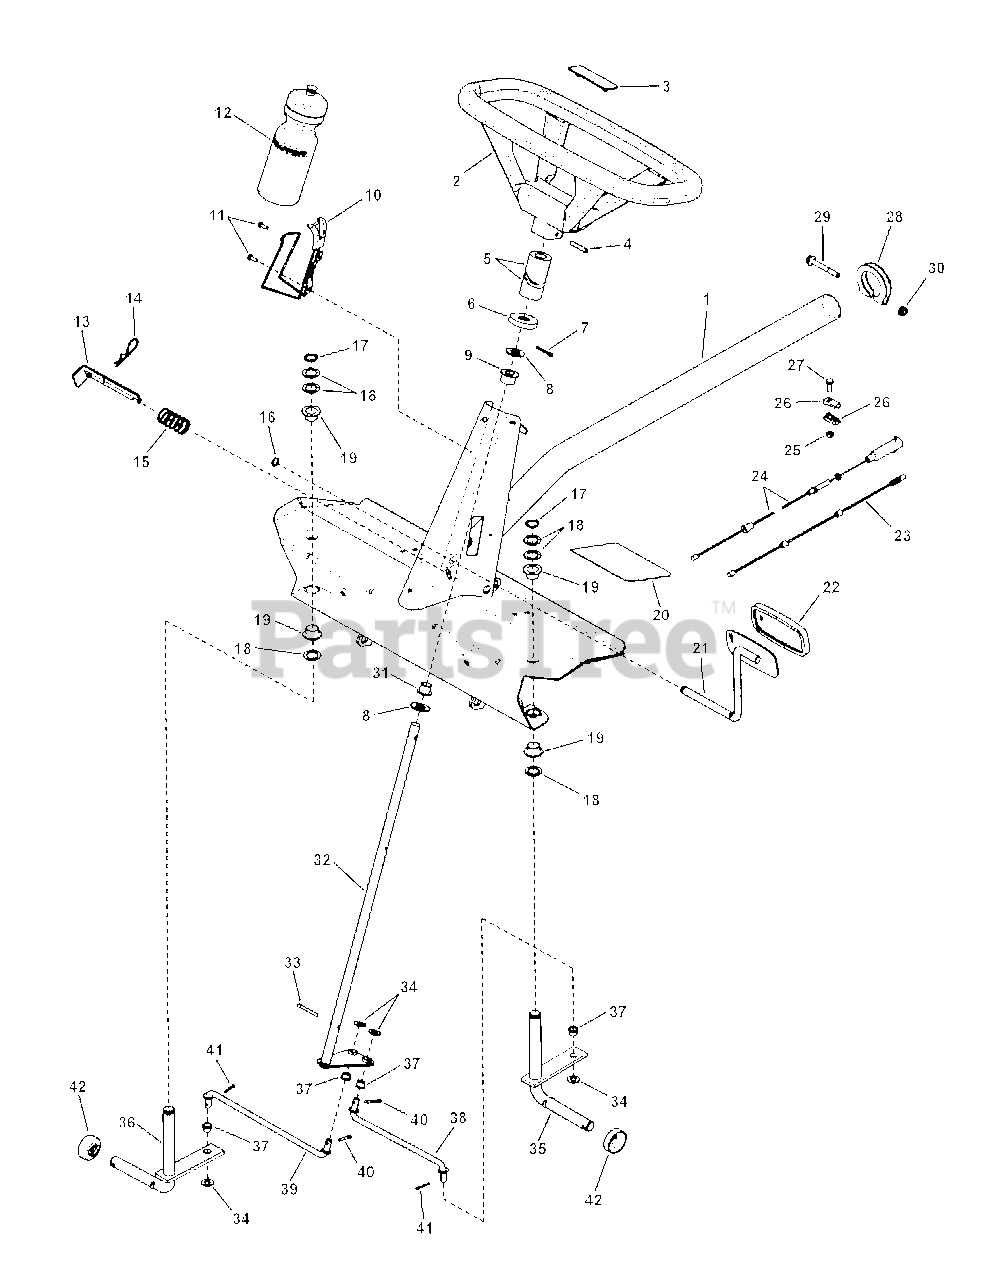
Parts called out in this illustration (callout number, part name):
1	WELDMENT, Front Axle, Wide
2	ASSEMBLY, Steering Wheel (for 5/8" shaft)
3	LOGO, Steering Wheel
4	ROLL PIN, 1/4 x 1-1/2"
5	FOAM COVER, Steering Shaft
6	COVER, Steering Shaft
7	PIN, 3/16 x 1" Cotter
8	WASHER, .66 x 1.31 x .09 Flat
9	BUSHING, Nylon
10	HOLDER, Bottle (Wire)
11	SCREW, #10-24 x 1/2" Hex Washer Self-Tap (Torx)
12	BOTTLE, Water
13	LATCH, Parking Brake
14	HAIR PIN, 2-1/4"
15	SPRING, Parking Brake Latch
16	RING, 1/2" External Retaining (Heavy Duty)
17	RING, 5/8" External Retaining
18	WASHER, .77 x 1.13 x .06 Flat
19	BEARING, Nylon
20	FOOT PAD, (Wide)
21	WELDMENT, Clutch Pedal
22	PAD, Pedal
23	CABLE, Clutch/Brake (55" long)
24	CABLE, Brake, Snap-In (Approx. 29.25" Long)
25	NUT, 1/4-20 Hex Center Lock, GR 5 or B
26	CONNECTOR, Cable
27	SCREW, 1/4-20 x 3/4" Hex Head Cap, GR 5
28	TUBE CLAMP
29	SCREW, 5/16-24 x 2-1/2" Hex Head Cap, GR 5
30	NUT, 5/16-24 Flange Lock (Large)
31	BUSHING, Nylon
32	WELDMENT, Steering Shaft
33	PIN, 3/16 x 1-1/2" Cotter
34	WASHER, 3/8" Flat SAE
35	WELDMENT, King Pin, Left Hand
36	WELDMENT, King Pin, Right Hand
37	BUSHING, Tie Rod
38	TIE ROD, Left Hand (9.91" long)
39	TIE ROD, Right Hand (9.91" long)
40	PIN, 5/32 x 1" Cotter
41	PIN, 1/8 x 3/4" Cotter
42	CAP, Dust
